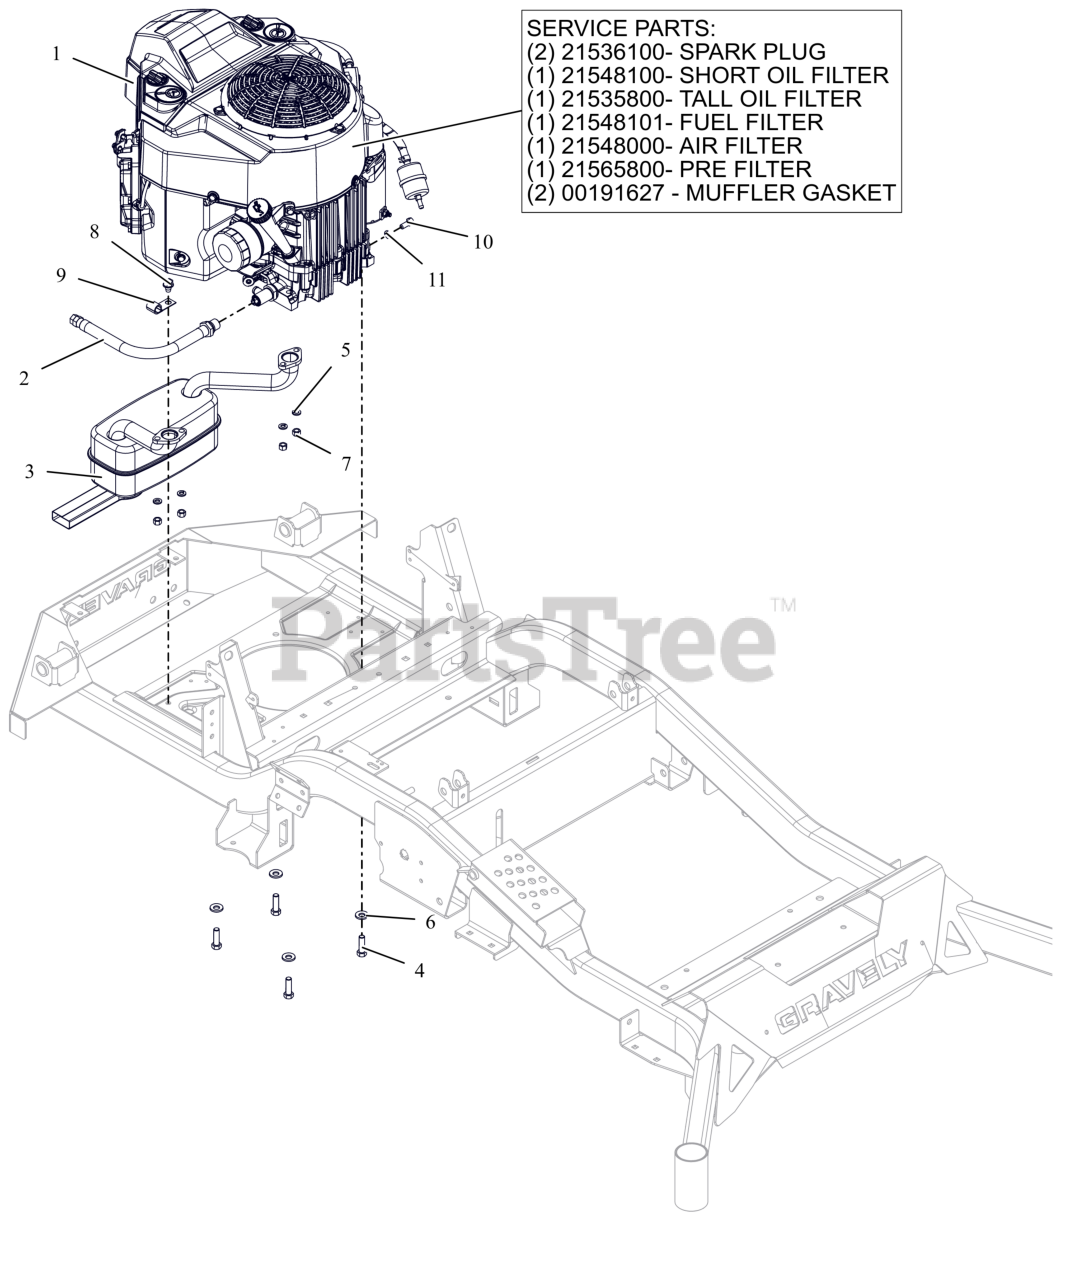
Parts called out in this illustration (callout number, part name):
1	ENGINE, KAWASAKI FS730V
1	PLUG, SPARK
1	OIL FILTER, KAWASAKI FR
1	FILTER,OIL - KAW
1	FUEL FILTER-KAWASAKI FR
1	AIR FILTER, KAWASAKI FR
1	PRE FILTER, KAWASAKI FS
1	GASKET, MUFFLER S/O
2	HOSE, OIL DRAIN
3	MUFFLER, KAWASAKI
4	BLT, HEX .38-16X1.25 G5 ZCC NT
5	WSHR,LK-REG .312X.078 ZCC
6	WASHER, 3/8" SPRING DISC
7	NUT-LK-TOP-FLG M8 ZCC
8	SCR,TAP .375-16X.50 HWH TR ZCC
10	BLT, HEX M8-1.25X20 G8.8 ZCC
11	WSHR,LK-REG .312X.078 ZCC
